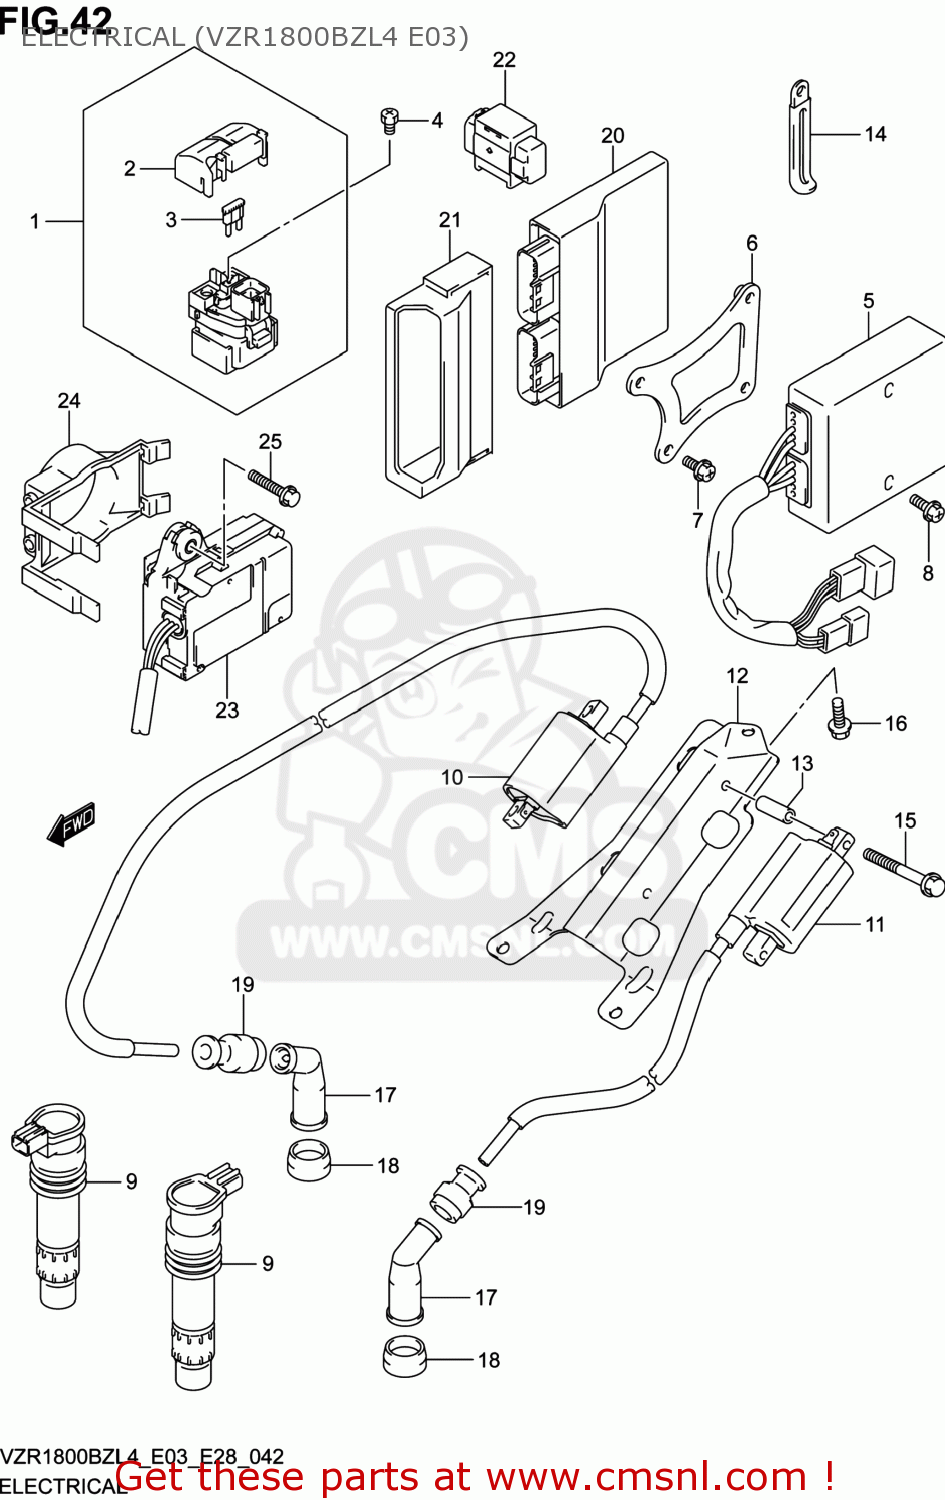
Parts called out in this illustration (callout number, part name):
1	RELAY ASSY,STARTING MOTOR
2	COVER
3	FUSE(30A)
4	SCREW(6X8)
5	RECTIFIER ASSY
6	BRACKET,RECT FIG
7	SCREW
8	SCREW
9	COIL ASSY,IGNITION
10	COIL ASSY,IGNITION RR
11	COIL ASSY,IGNITION RR
12	BRACKET,IGNITION COIL
13	SPACER(6.4X10X18)
14	CLAMP(L:80)
15	BOLT
16	BOLT
17	CAP ASSY,SPARK PLUG
18	SEAL,SPARK PLUG
19	SEAL,HIGH TENSION CORD
20	CONTROL UNIT,FI
21	HOLDER,FI CONTROL UNIT
22	SENSOR ASSY,FUEL CUT
23	ACTUATOR ASSY,EXHAUST CONTROL
24	COVER,ACTUATOR
25	BOLT
